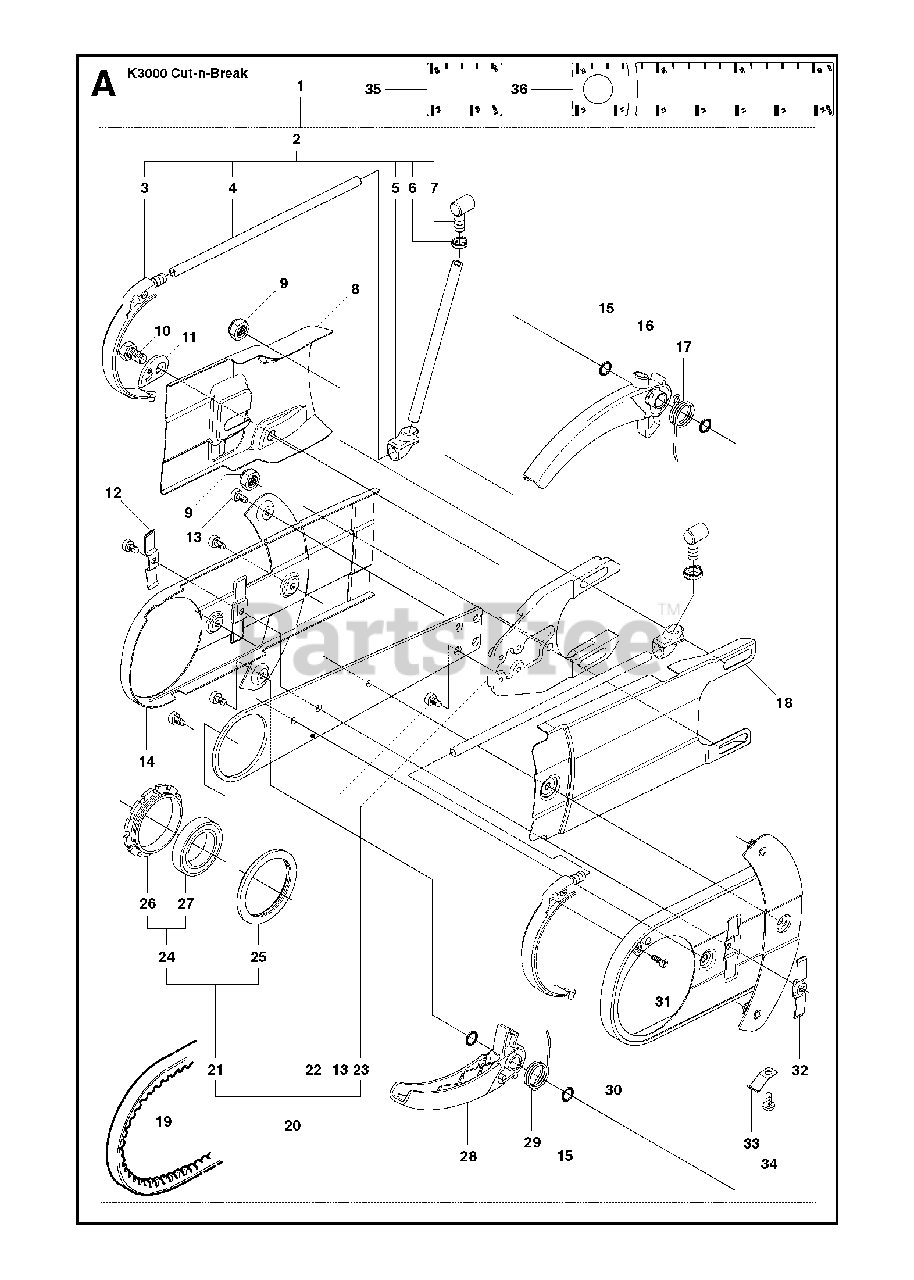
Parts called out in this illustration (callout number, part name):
1	CUTTER ARMIncl. 2 - 34
2	HOSEIncl. 3 - 7
4	HOSE
9	HEXAGON NUT
12	DEFLECTION LIMITER
13	SCREW ITXSCM
20	BAR PLATEIncl. 13, 21 - 23
24	BEARING CAGEIncl. 26 - 27
26	BEARING CAGE
31	SCREW CCRPANT
32	DEFLECTION LIMITER
34	SCREW CRPANM
